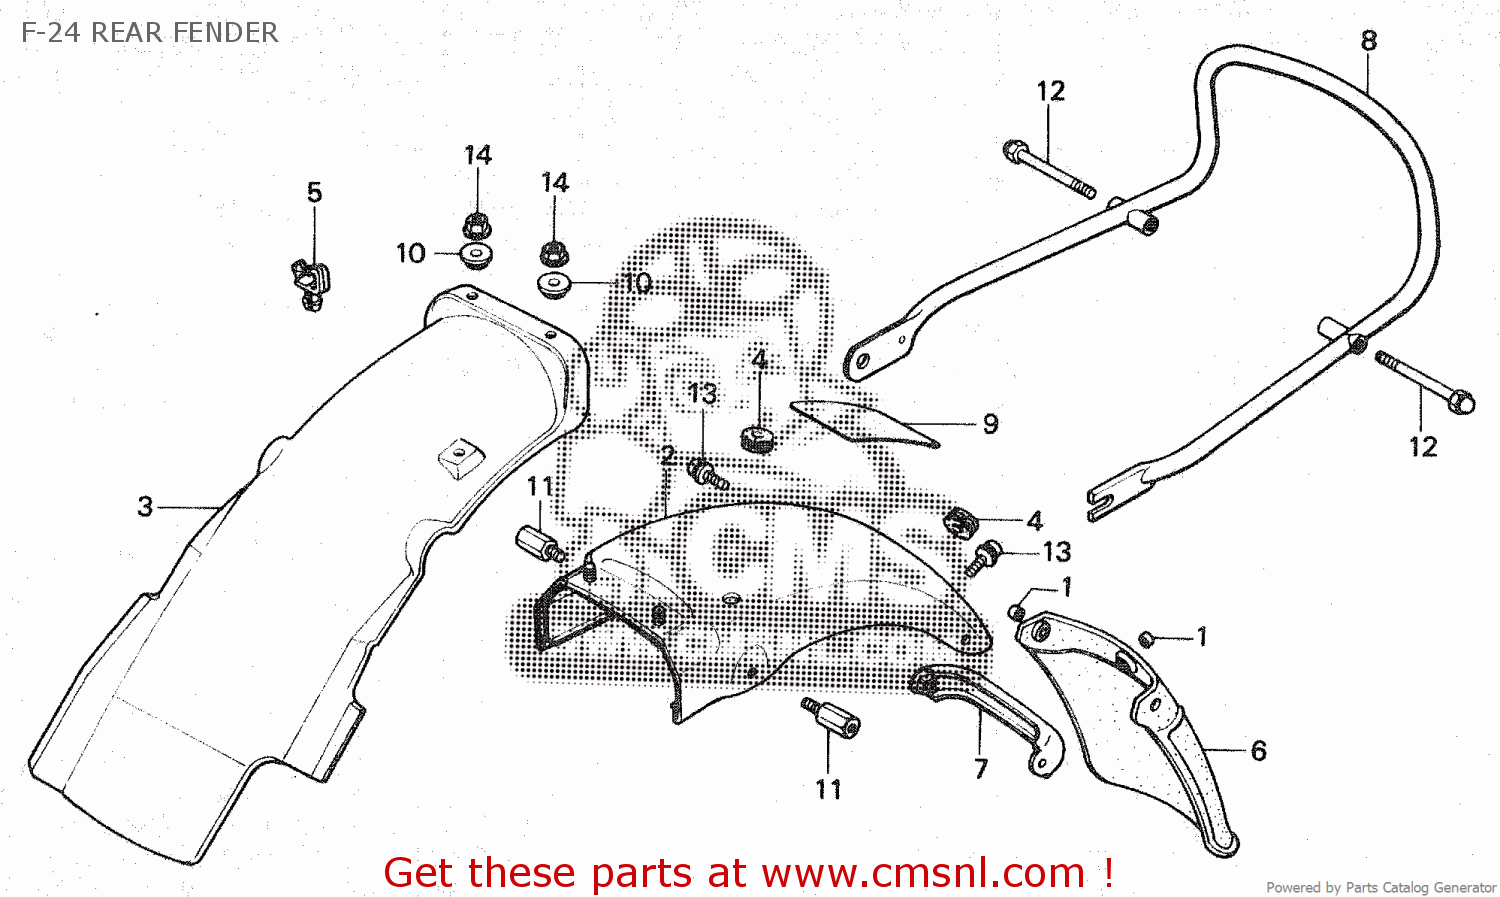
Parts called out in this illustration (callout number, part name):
2	FENDER A,RR.
3	FENDER B,RR.
4	GROM,TAILLIGHT
5	CLAMP, CABLE
6	MUDGUARD,RR,FENDE
7	STAY,MUDGUARD
8	BUMPER,RR.
9	MARK,ACC LOAD
10	WASHER,6X20
11	BOLT,BPR.SETTING
12	BOLT,HEX,CAP,8X50
13	SCREW-WASHER 6X16
